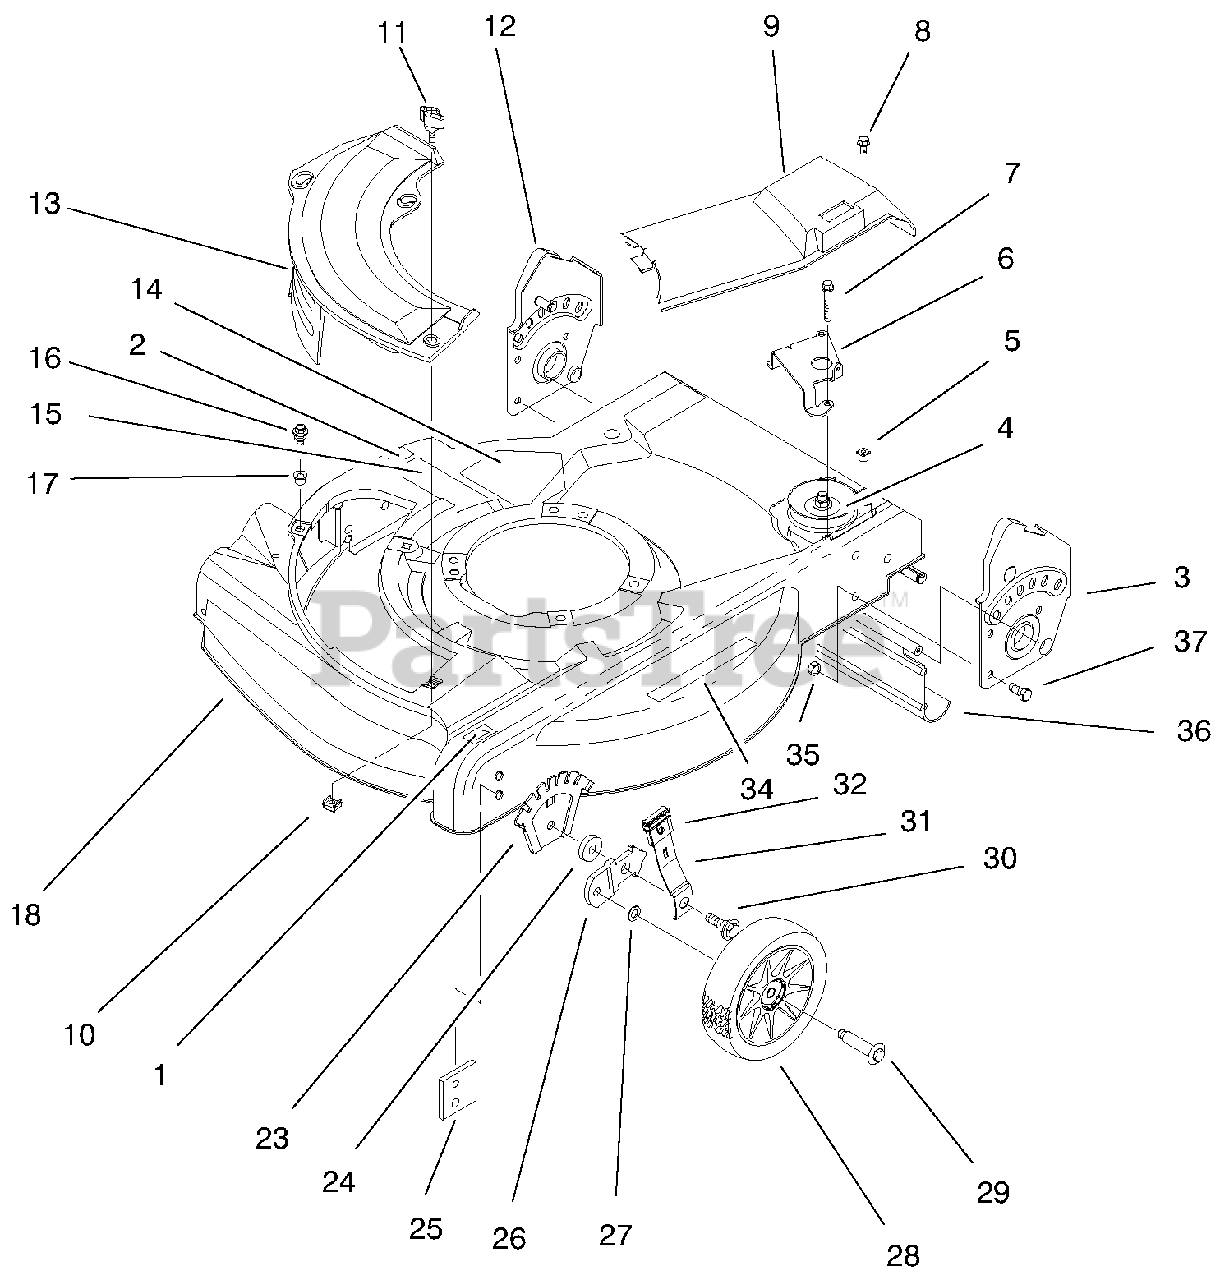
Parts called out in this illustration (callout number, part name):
1	Decal-HOC
2	Decal-HOC
3	ASM-Handle Bracket
4	ASM-Gear Case
5	Grommet
6	Guide-Transmission
7	Screw-Thread Forming
8	Screw-Phil
9	Cover-Drive
10	Nut-Cage
11	Knob-Cover Plate
12	ASM-Handle Bracket
13	Mulch Plate-21"
14	Decal-Danger
15	Decal-Discharge
16	Screw-Sems
17	Grommet-Plastic
18	ASM-Housing & Baffle
23	Plate-Height Adjust
25	Plate-Baffle
26	Bracket-Wheel Height Adj
28	ASM-Wheel & Tire 6"
29	Bolt-Shoulder
30	Bolt-Shoulder
31	Spring Arm-Front
32	Knob-Height Adjust
34	Decal-Warning
35	Nut-Lock
36	Shield-Trailing
37	Screw-HH
